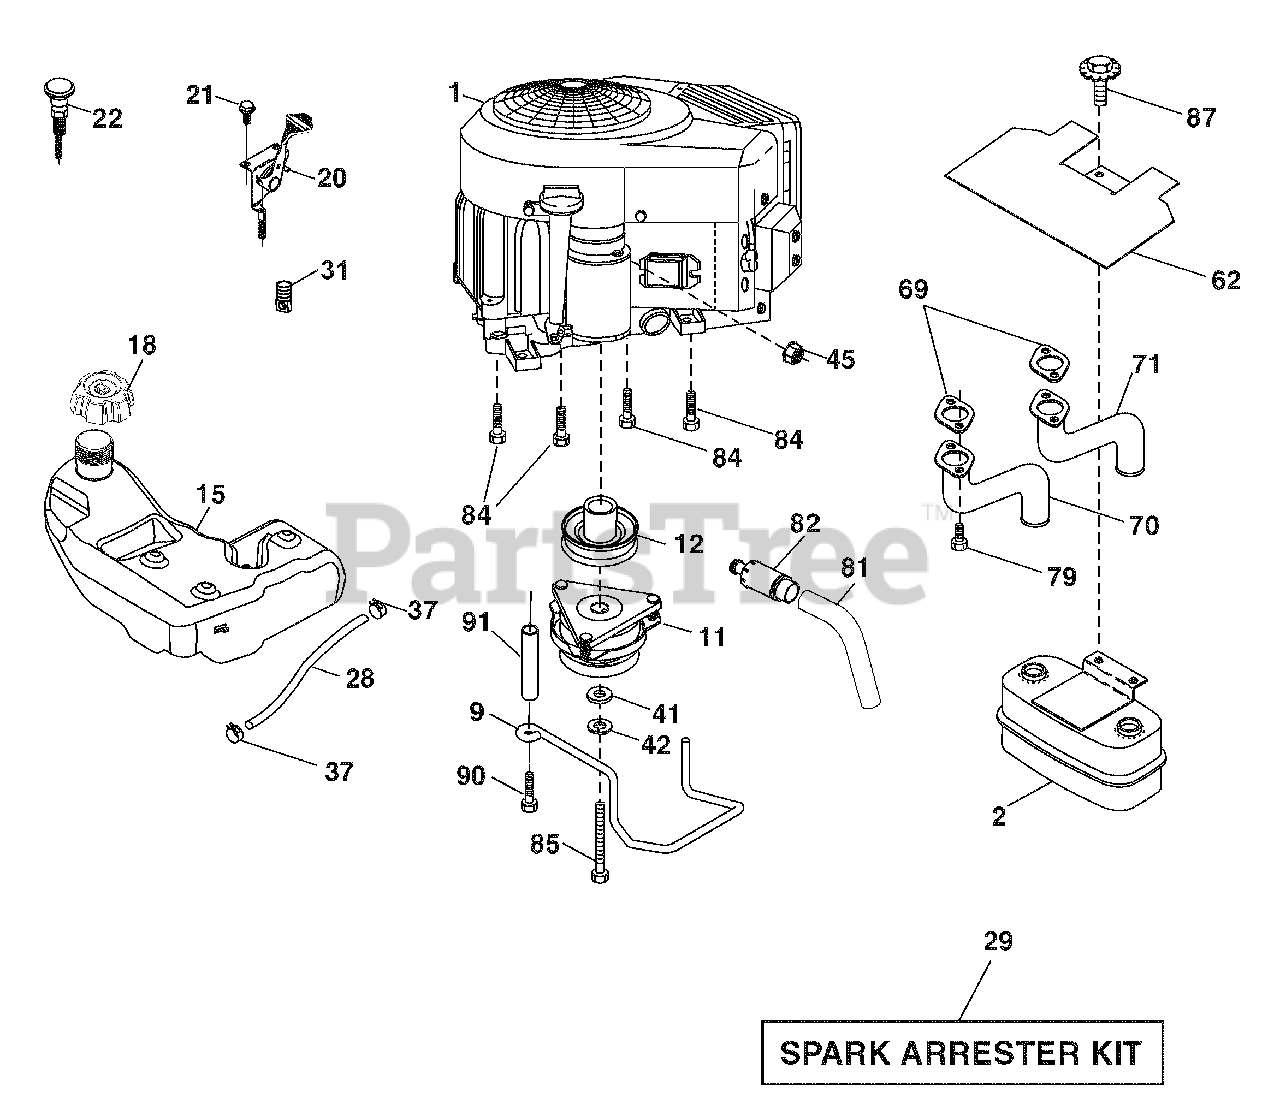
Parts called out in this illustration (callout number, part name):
9	Keeper Asm. Belt Engine
11	Clutch Electric
12	Pulley Engine
15	Tank Fuel 4.0
18	Cap Asm
20	Control Throttle
21	Screw #10 x 0.750 BOS Thread
22	Control Choke
28	Fuel Line
29	Spark Arrester Kit
31	Clip Push-In
37	Clamp Hose
41	Washer 1-1/2 OD x 15/32 ID x .250
42	Washer Lock 7/16
45	Nut Keps Hex 1/4-20 unc
62	Shield Heat Muffler
70	Tube Exhaust LH
71	Tube Exhaust RH
79	Screw Socket HD 5/16-18 x 1
81	Tube Drain Oil Easy
82	Plug Drain Oil Easy
84	Screw 3/8-16 x 1-1/4
85	Bolt 7/16-20 x 3.75 Gr. 5
87	Bolt 5/16-18 unc x 1 w/Sems
90	Screw 3/8-16 x 1
